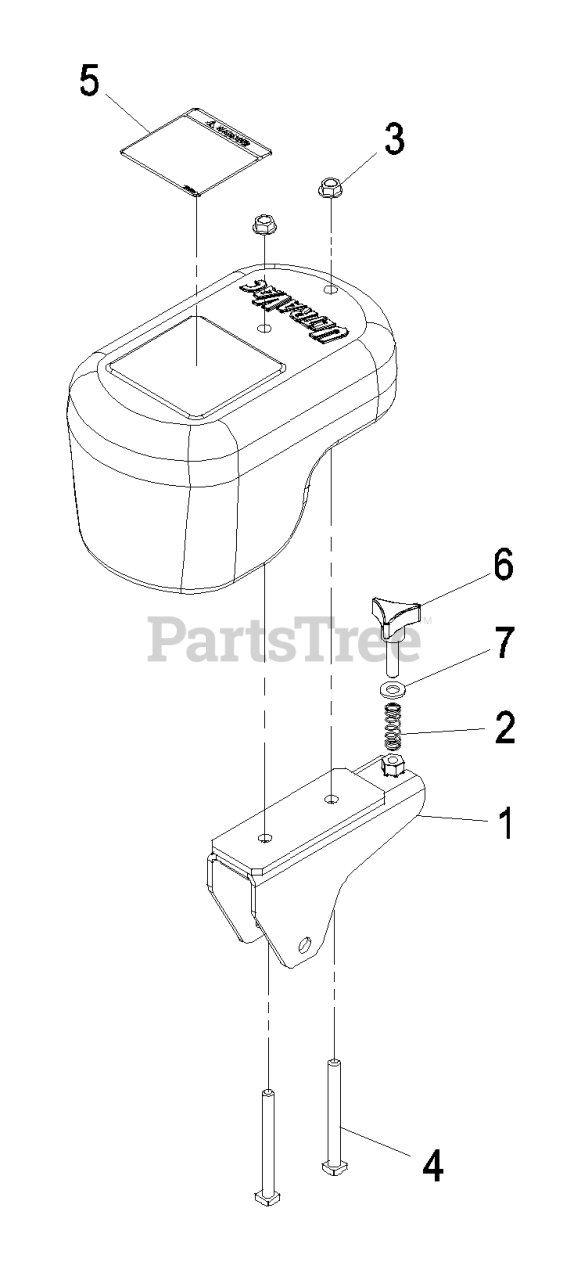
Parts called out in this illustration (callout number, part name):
1	ASM,CASTER WEIGHT BRACKET
3	NUT-HHF, WHIZ
4	BOLT, SQUARE HEAD YZ
5	DECAL,WEIGHT
7	WASHER-FLAT
